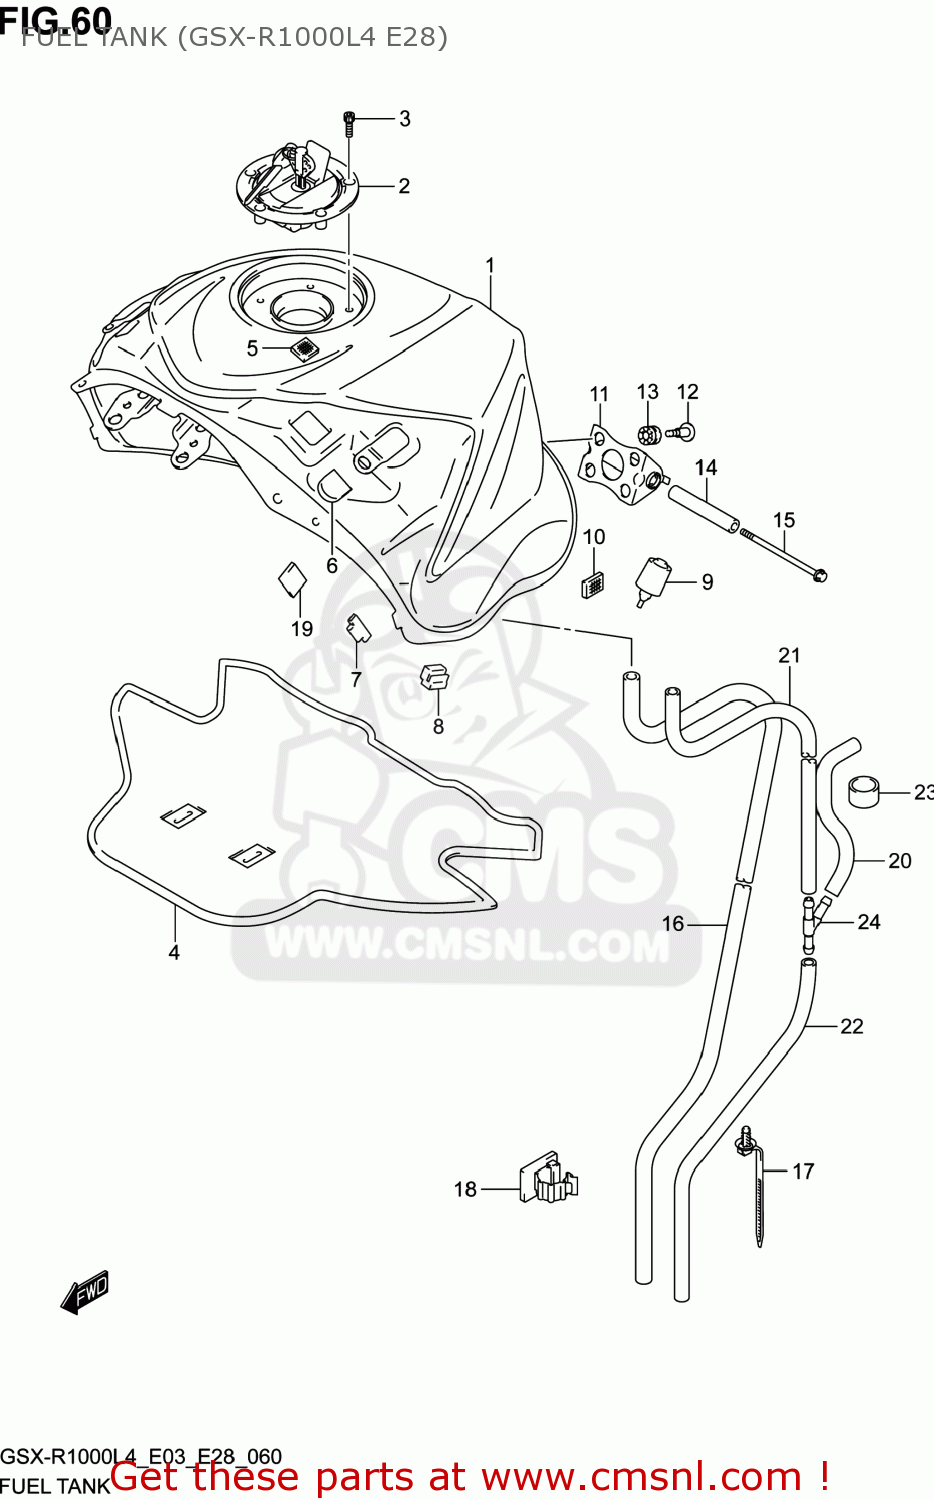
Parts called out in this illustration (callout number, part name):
1	TANK ASSY,FUEL(BLUE)
2	CAP SET,FUEL TANK
3	BOLT(5X20)
4	SHIELD,FUEL TANK HEAT
5	FASTENER
6	CUSHION
7	CUSHION,FUEL TANK COVER
8	CUSHION,FUEL TANK SIDE
9	CUSHION,FUEL TANK RR
10	FASTENER
11	BRACKET,FUEL TANK NO.1
12	SCREW(6X22)
13	CUSHION
14	SPACER,FUEL TANK RR
15	BOLT(6X110)
16	HOSE,FUEL TANK WATER DRAIN
17	CLAMP(L:154)
18	CLAMP
19	PAD
20	HOSE,TANK BREATHER NO.2
21	HOSE,FUEL TANK BREATHER NO.1
22	HOSE,FUEL TANK BREATHER NO.2
23	HOSE(12X16X600)
24	3 WAY
